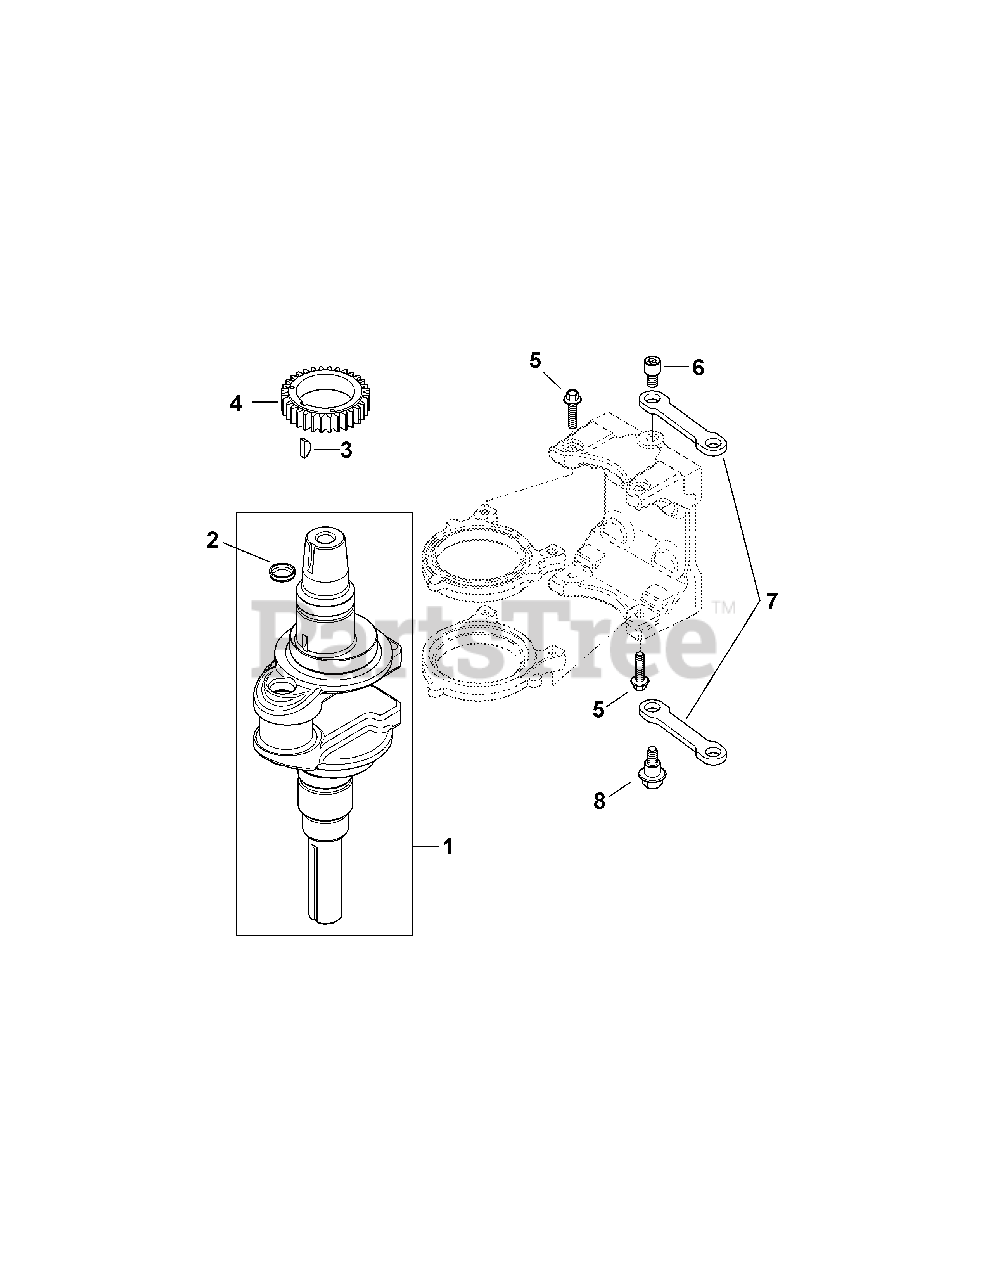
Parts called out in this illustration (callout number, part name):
1	Crankshaft Assembly Kit (Inc. 2)
3	Key, 3/16 x 5/8
4	Crankshaft Gear
5	Flange Screw, M6 x 1.0 x 25
6	Link Pivot Screw
7	Balance Weight Linkage
8	Shoulder Screw
